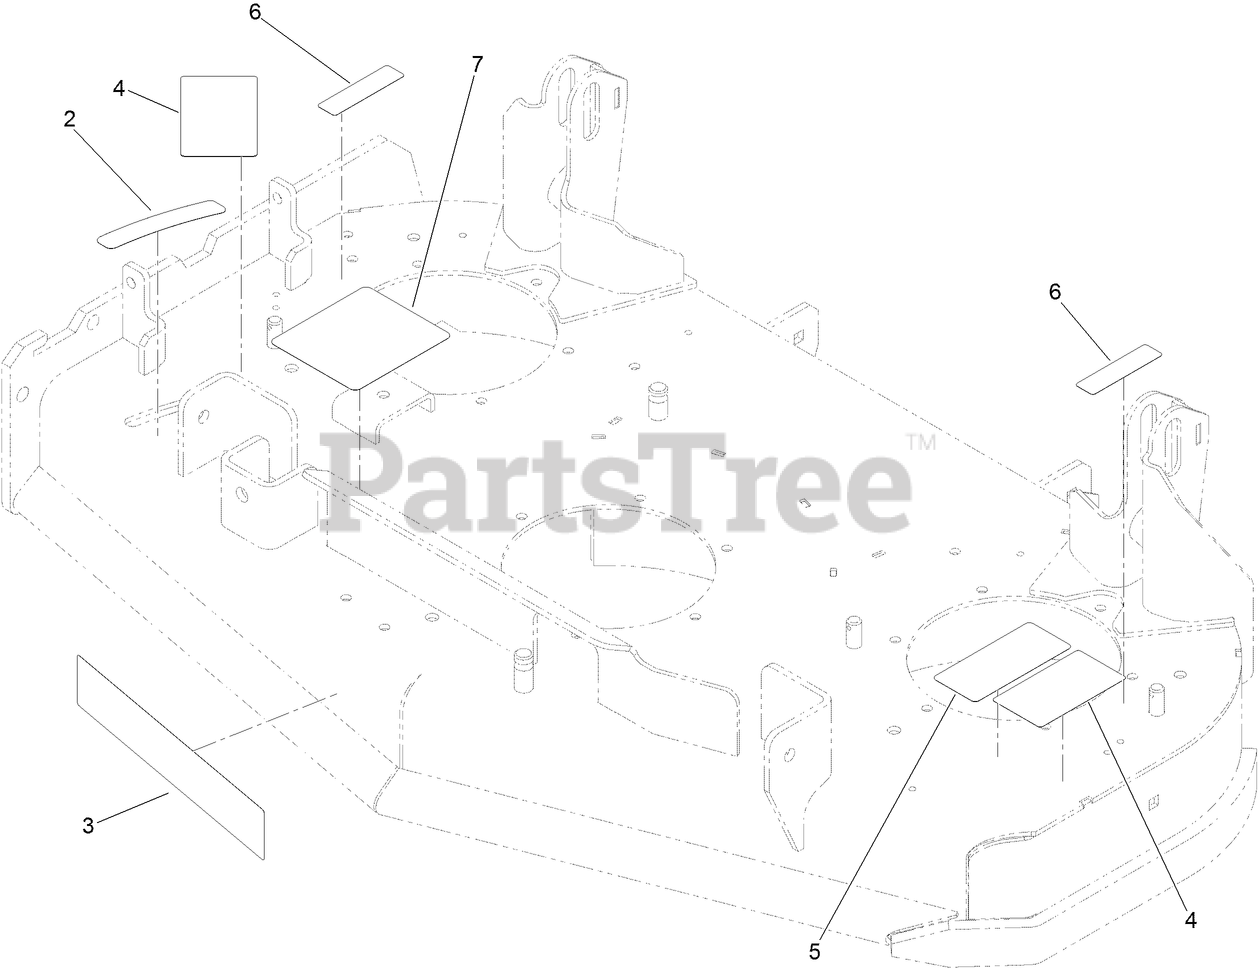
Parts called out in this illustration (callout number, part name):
2	DECAL-SETTING, BAFFLE
4	DECAL-DANGER
5	DECAL-TORQUE, BLADE BOLT
6	DECAL-DANGER
7	DECAL-ROUTING, BELT
